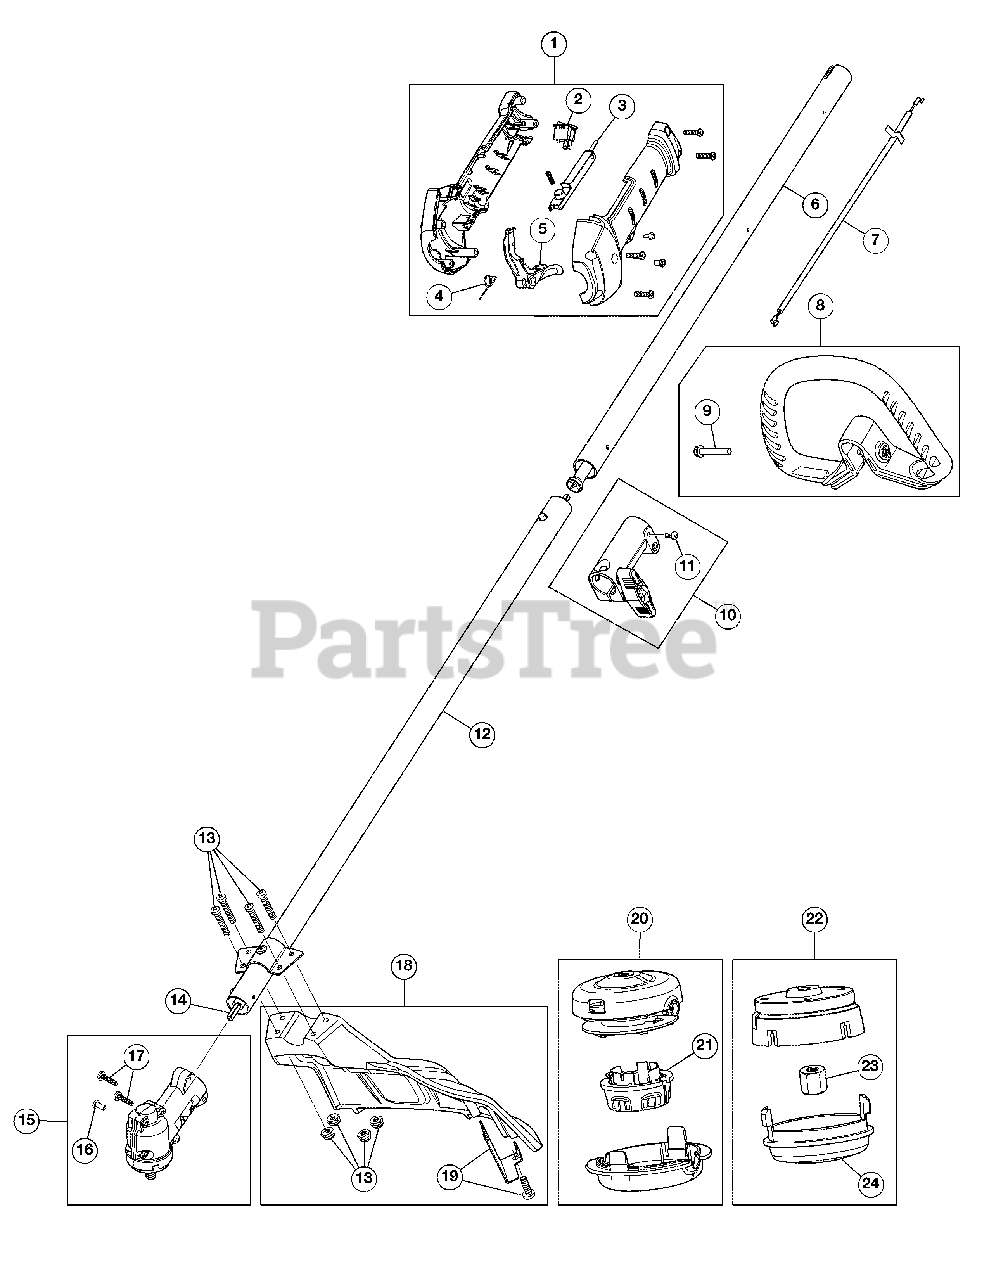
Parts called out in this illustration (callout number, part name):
1	Throttle Housing Assembly (Incl. 2 - 5)
2	Trigger Switch Assembly
3	Throttle Lock-out
4	Throttle Trigger Spring
5	Throttle Trigger
6	Upper Drive Shaft Assembly
7	Throttle Cable
8	D-Handle Assembly (Incl. 9)
10	Split Boom Coupler (Incl. 11)
11	Coupler Anti-Rotation Screw
12	Lower Drive Shaft Housing Assembly
13	Shield Mounting Screws and Nuts
14	Lower Flexible Drive Shaft
15	Gearbox Assembly (Incl. 16 - 17)
16	Gearbox Anti-Rotation Screw
17	Gearbox Mounting Hardware
18	Shield Assembly (Incl. 19)
19	Blade Assembly
20	Cutting Head Assembly (Incl. 21)
22	Aero Flex Cutting Head (Incl. 23 and 24)
24	Aero Flex Cap
